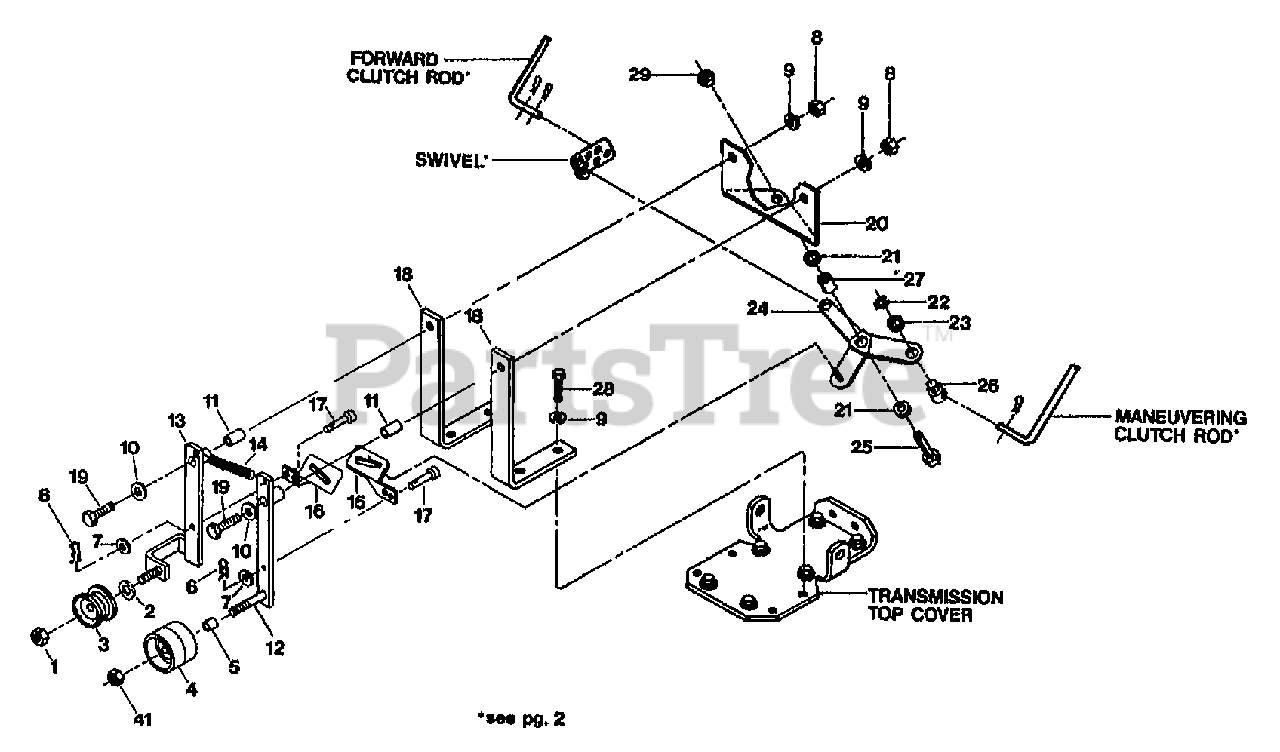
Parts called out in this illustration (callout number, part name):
1	NUT-LOCK 3/8-16 NYLON ZP
2	BUSHING-.54X.38X.08
3	IDLER-REV
4	PULLEY-FWD IDLER
5	BUSHING-.5X.375X.3
6	PIN-CLIP .08
7	WASHER-FLAT 1/4 SAE
8	NUT-HEX 5/16-18 ZP
9	WASHER-LK .312 ZP
10	WASHER-#.75X.32X.09 ZP
11	BUSHING-.438X.323X.712
12	ARM-IDLER FWD PNT
13	IDLER-REV
14	SPRING-.436 X 3.25
15	LINK-FWD
17	PIN-CLEVIS .375X.719 ZP
18	MOUNT BAR-PNT (20691)
19	BOLT-HH 5/16-18 X 2 G5 ZP
20	SHIFT BASE-OPC PNT
21	SPACER-.88X.385X.09 ZP
22	RING-KLIP .500 ZINC
23	WASHER-#.88X.51X.063 ZP
24	BELLCRANK-OPC PNT
25	SCR-HH 3/8-16X1.25
26	PIVOT-ROD
27	BUSHING-.5X.38X.4
28	SCR-HH 5/16-18X1.0 G5 ZP
29	NUT-H/LK 3/8-16
